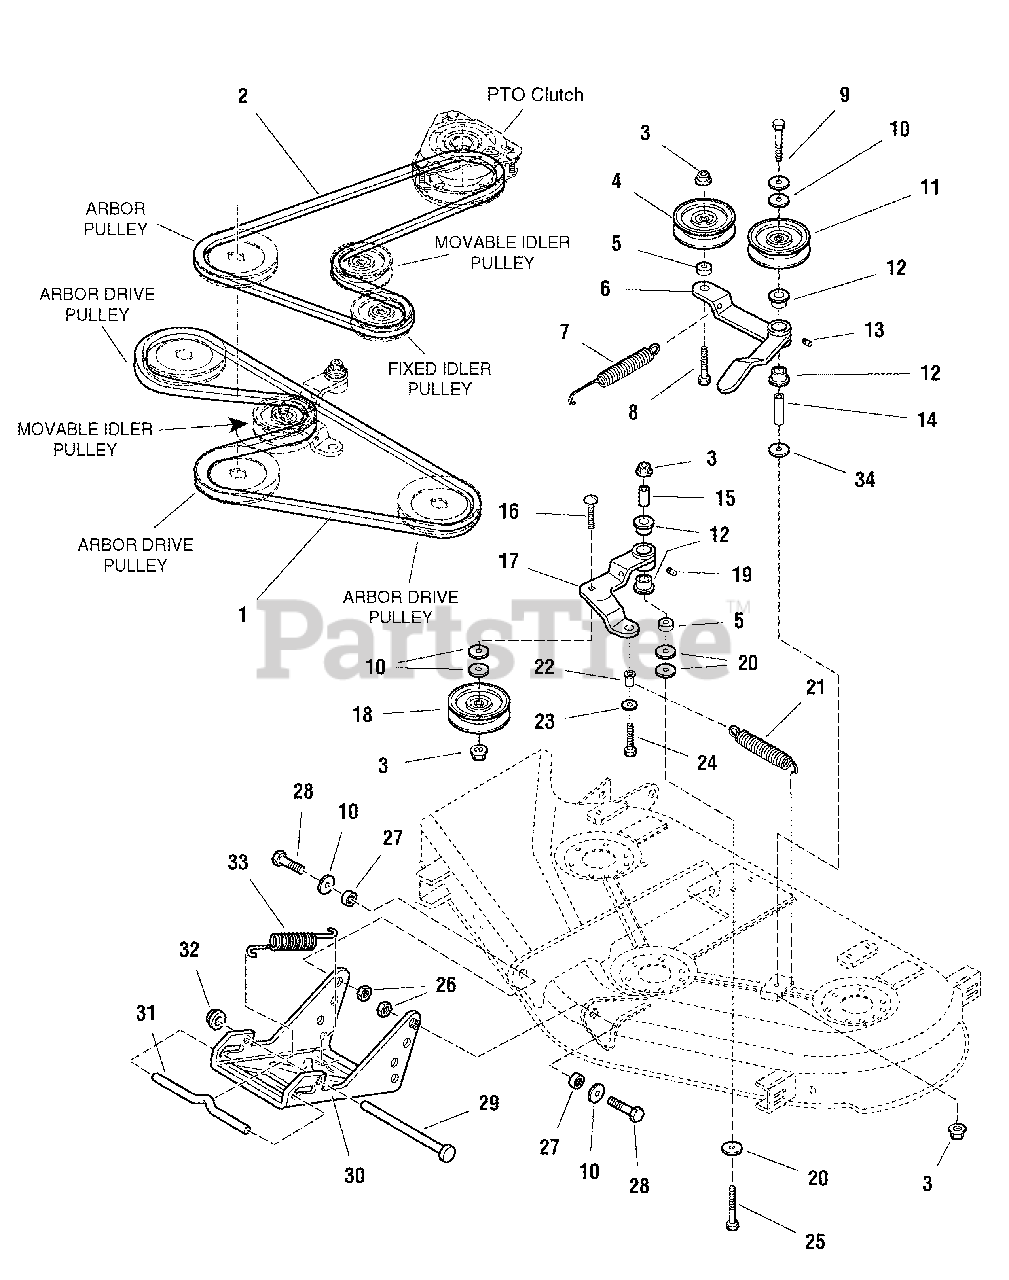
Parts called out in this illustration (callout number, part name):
1	V-BELT, Mower Deck, 44" Mower Deck
2	V-BELT, P.T.O., 44" Mower Deck
3	NUT, Hex Flange, 3/8-16
4	PULLEY, Idler
5	SPACER, Powdered Metal
6	LEVER & HANDLE ASSEMBLY, (Includes Ref. Nos. 12 & 13)
7	SPRING, Extension
8	CARRIAGE BOLT, 3/8-16 x 1-3/4 G5, Black
9	CAPSCREW, 3/8-16 x 3-1/4
10	WASHER, 3/8
11	PULLEY, Idler (Includes Ref. Nos. 12 & 13)
13	FITTING, Lube, 1/4-20 Tappered
14	SPACER, Hardened
15	SPACER, Hard Case
16	CARRIAGE BOLT, 3/8-16 x 1-1/4, G5
17	LEVER ASSEMBLY, Idler (Includes Ref. Nos. 12 & 19)
18	PULLEY, Idler
19	FITTING, Lube, 1/4 Drive
20	WASHER, 3/8
21	SPRING, Extension
23	WASHER, 1/4
24	CAPSCREW, Hex Head, 1/4-20 x 1-1/6
25	CAPSCREW, Hex Head, 3/8-16 x 2-1/2, G5
26	NUT, Hex Lock ESNA Light, 3/8-16
27	SPACER, Powdered Metal
28	CAPSCREW, 3/8-16 x 1-1/4, G8
29	ROD, Hitch, 1/2 x 7-5/8
32	NUT, Push 1/2
33	SPRING
34	WASHER
